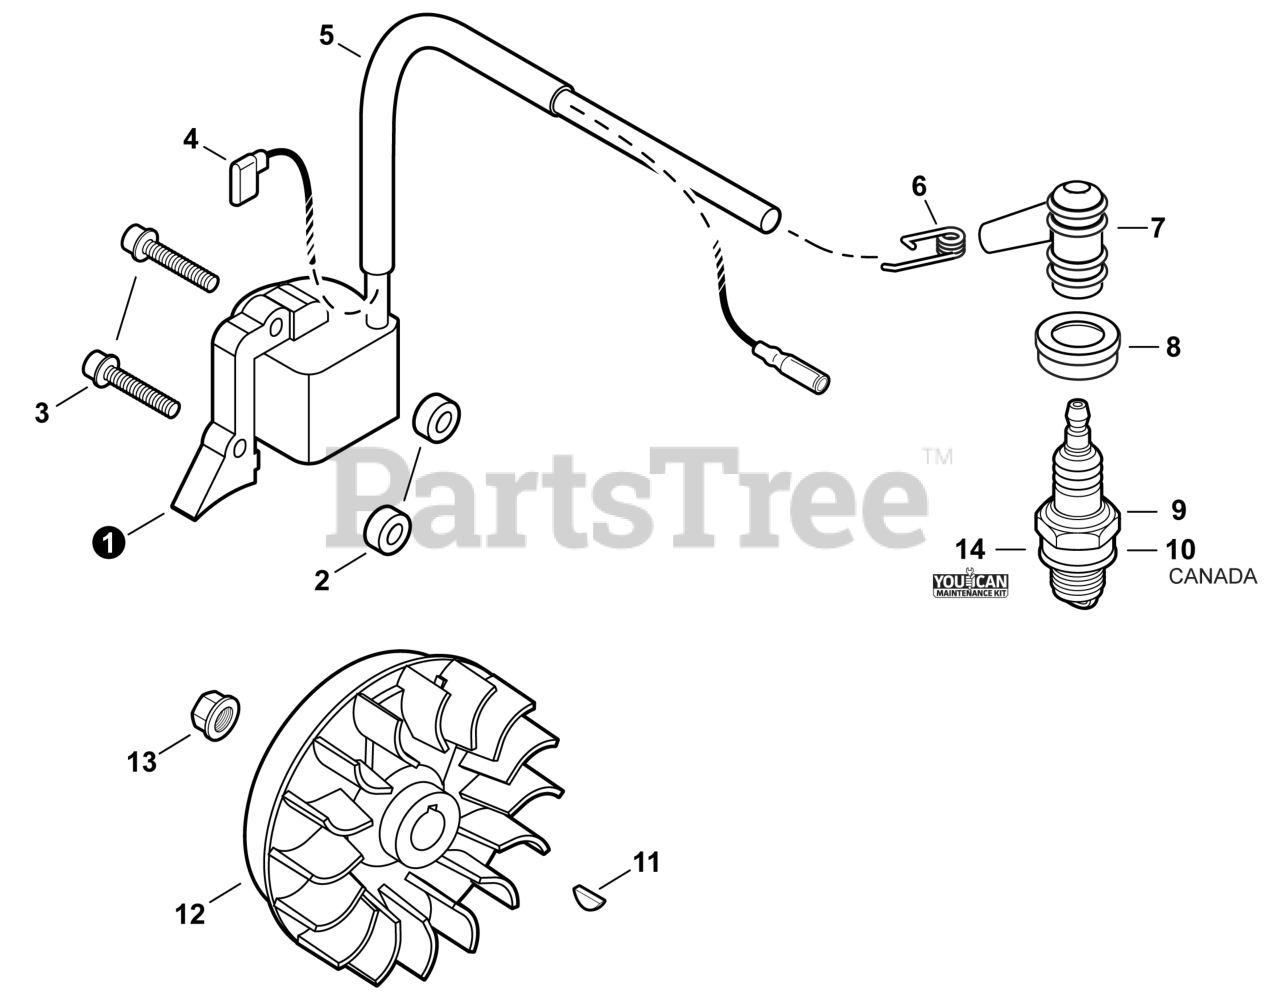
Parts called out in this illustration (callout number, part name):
1	COIL, IGNITION
2	INSULATOR 4.2×11×6
3	BOLT, ADHESIVE M4×24
4	LEAD - IGNITION L= 180
5	TUBE, IGNITION COIL Ø8×L125
6	TERMINAL, SPARK PLUG
7	CAP, SPARK PLUG
8	SEAL, SPARK PLUG
9	SPARK PLUG - BPM8Y
10	SPARK PLUG - BPMR8Y
11	KEY, WOODRUFF 3×10
12	FLYWHEEL
14	TUNE-UP KIT - YOUCANT
